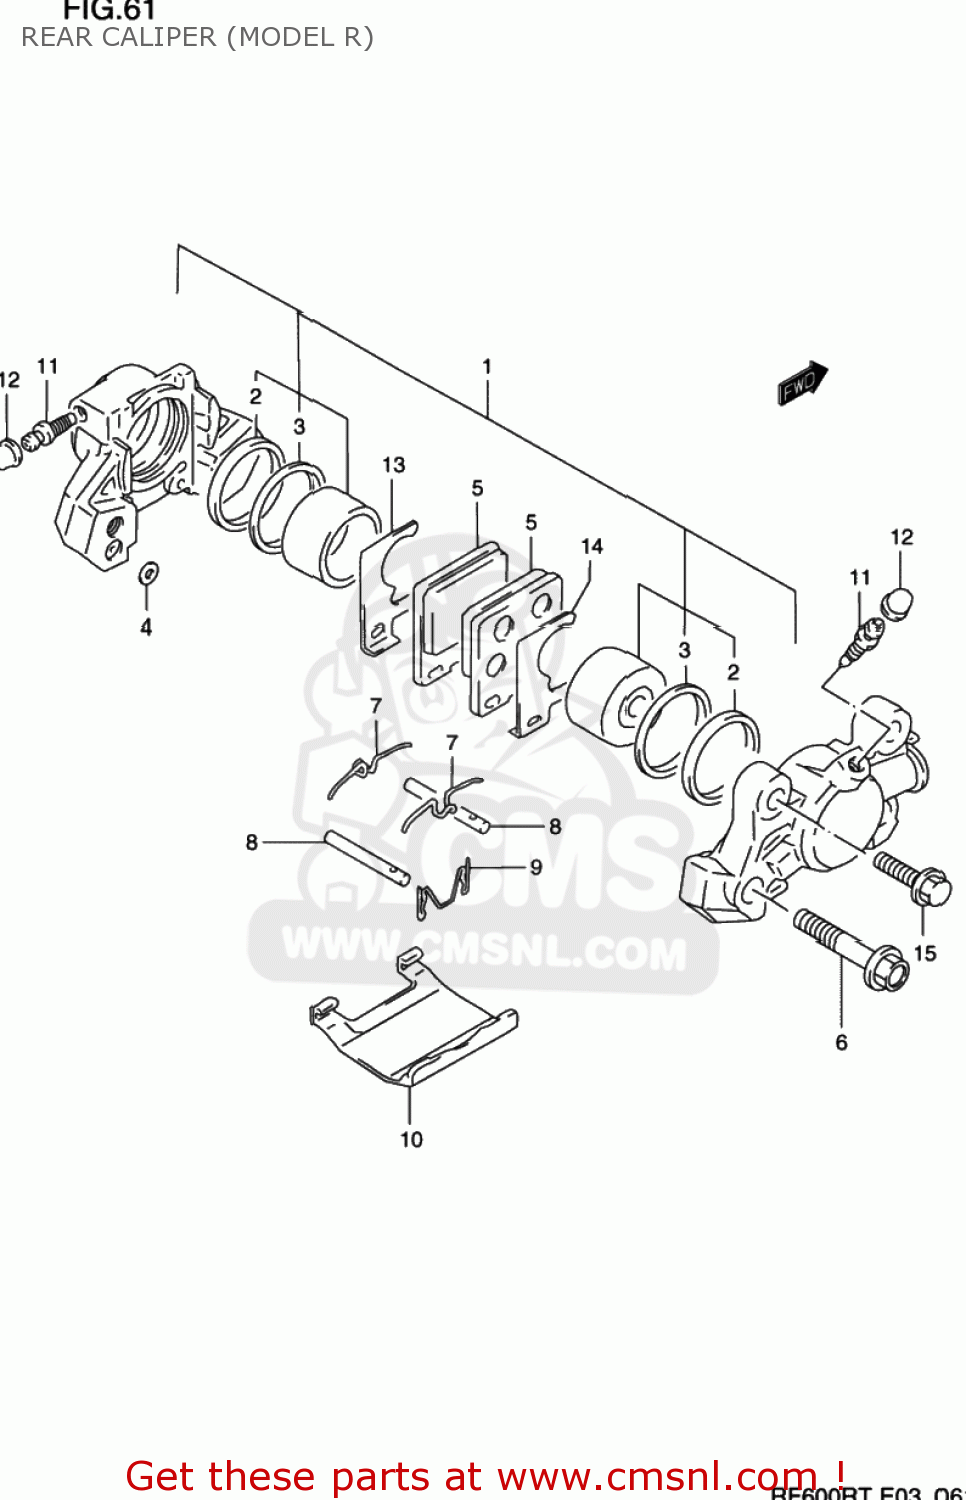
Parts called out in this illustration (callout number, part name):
1	PISTON SET
2	SEAL,PISTON
3	SEAL,WIPER
4	SEAL,JOINT
5	PAD,BRAKE
6	BOLT
7	SPRING
8	PIN,PAD
9	CLIP,PAD PIN
10	COVER
11	BLEEDER
12	CAP,BREATHER
13	SHIM,INNER
14	SHIM,OUTER
15	BOLT
